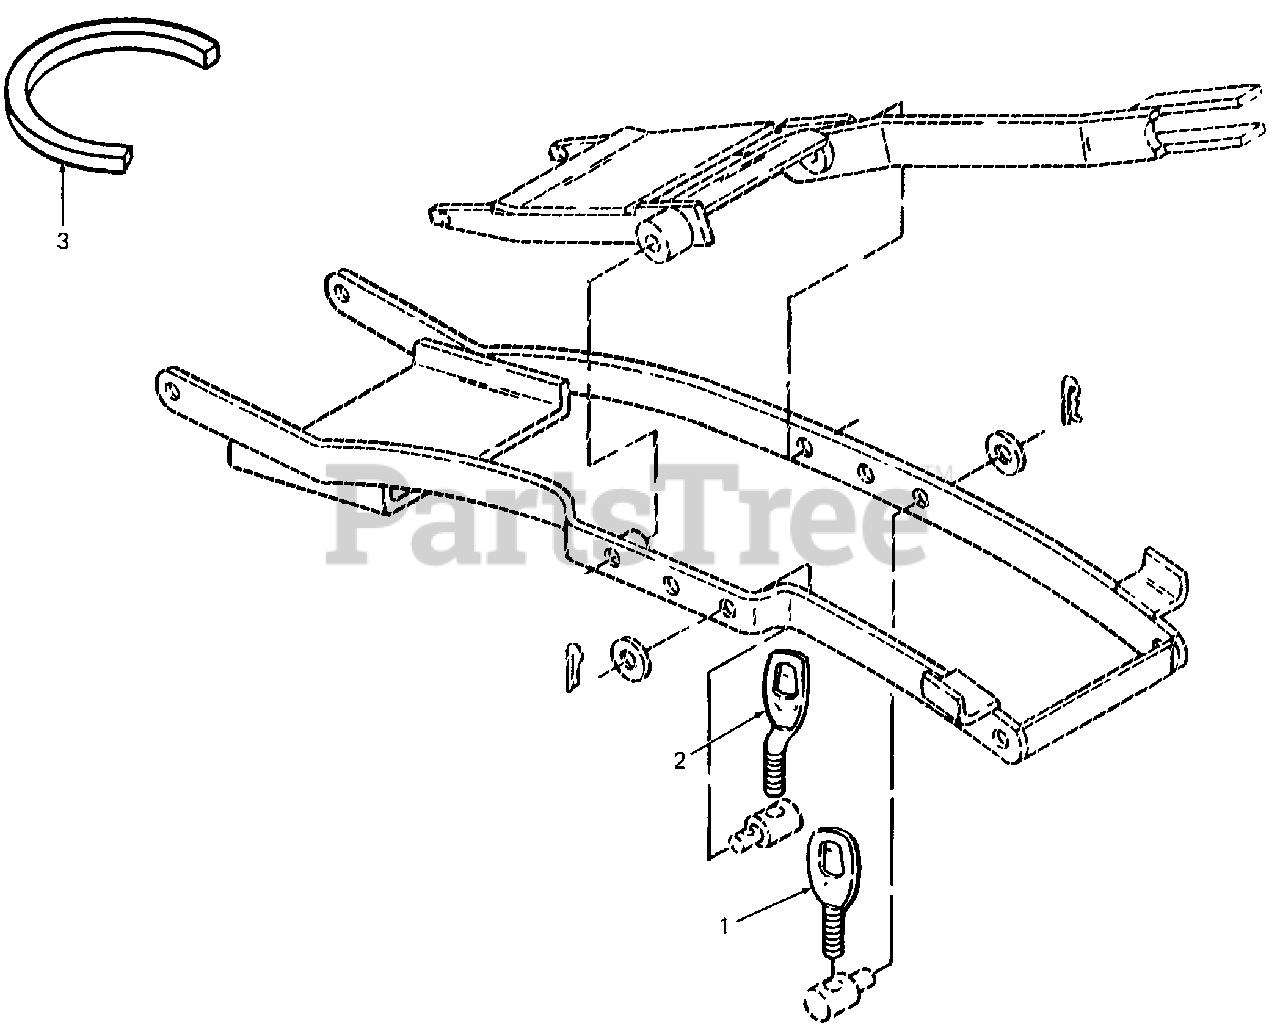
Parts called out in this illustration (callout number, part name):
1	Link, Adjustable
2	Link, Offset Adjustable
3	Belt, Mule Drive
